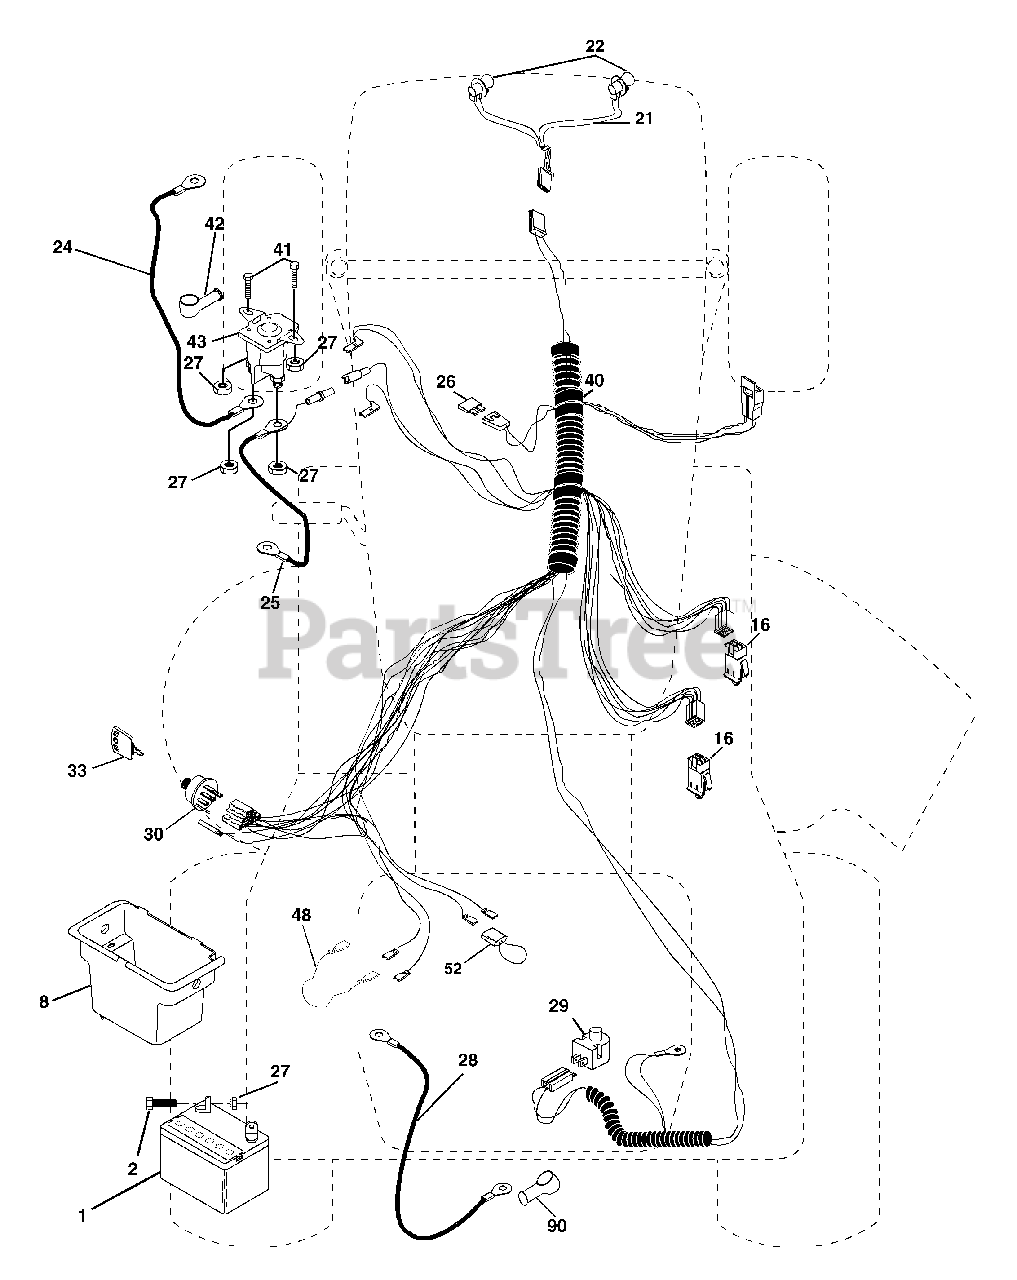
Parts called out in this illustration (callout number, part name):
1	Battery
2	Bolt Hex Hd 1/4-20 Unc x 3/4
8	Box Battery
16	Switch Interlock
21	Harness Asm Light W/4152j
22	Bulb Light #1156
24	Cable Battery 6 Ga 16" red
25	Cable Battery
26	Fuse 20 AMP
27	Nut Keps Hex 1/4-20 Unc
28	Cable Ground 6 Ga 12" black
29	Switch Plunger Nc Gray
30	Switch Ign
33	Key Ign
40	Harness Ign
41	Bolt Blk Fin Hex 1/4-20
42	Cover Terminal Red
43	Solenoid
48	Adapter Ammeter
52	Protection Wire Loop
90	Cover Terminal Battery
